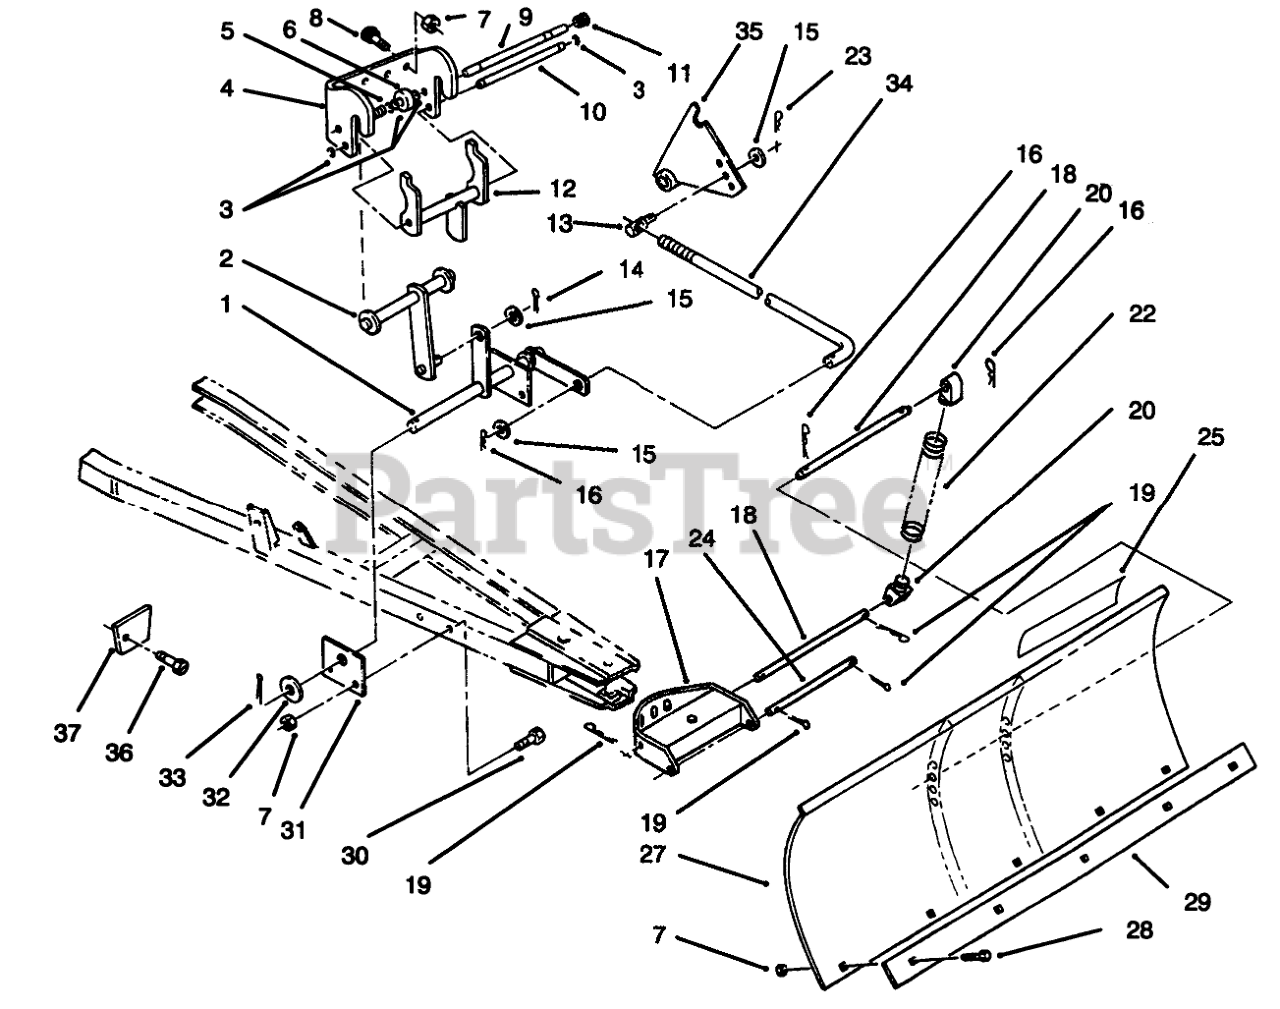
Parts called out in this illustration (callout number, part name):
1	Lift Arm
2	Arm
3	RING-RETAINING
4	HITCH-FRONT
5	SPRING
7	NUT-LOCK, NI
8	SCREW-CARR
9	ROD-LOCK
10	ROD-LATCH PIVOT
11	CAP-ROD, PLUNGER
12	LATCH
13	STUD-TRUNION
14	PIN-COTTER
15	WASHER-FLAT
16	Hairpin
17	QUADRANT
18	ROD-PIVOT, BLADE
19	PIN-COTTER
20	Lug
22	Spring-Return
23	Hairpin Cotter
24	ROD-LOWER
25	DECAL-ATTACHMENT
27	BLADE ASM
28	SCREW-CARR
29	PLATE - BLADE EDGE
30	SCREW-HH
32	WASHER-FLAT
33	PIN-COTTER
35	Plate
36	Screw
